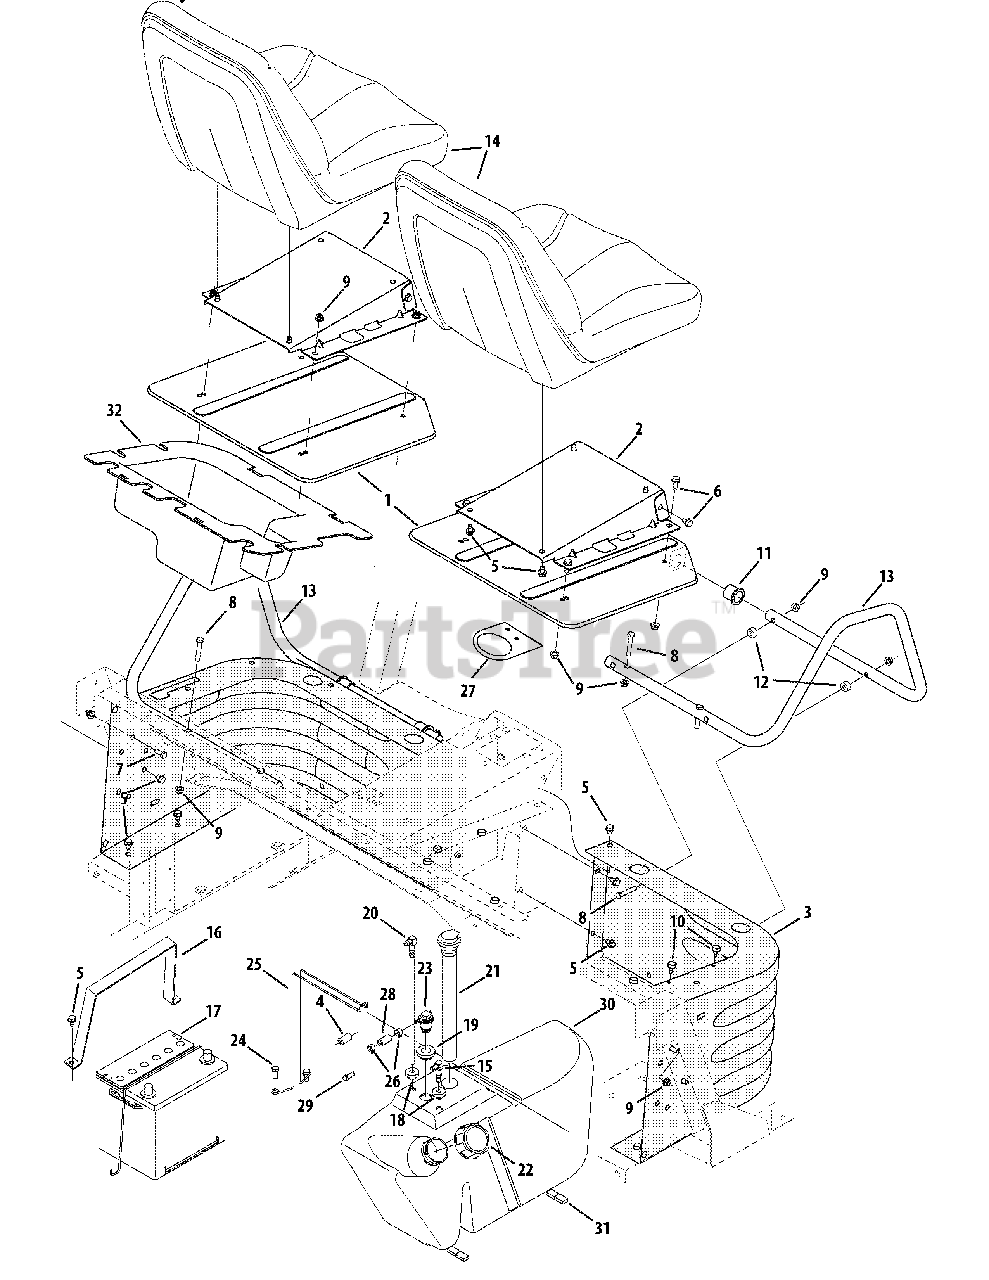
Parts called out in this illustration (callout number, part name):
1	Plt, Seat, Assm.
4	Line, Fuel, HP
5	Scr., TT, 5/16-18 x .500
6	Screw, LD, 5/16-18 x .750
7	Screw, 5/16-18 x .75
8	Screw, 5/16-18 x 1.75
9	Nut, Flglk, 5/16-18
10	Bmpr, .62 Dia. x .3
11	Brg, Flg, .894 ID x 1.1315 OD
12	Spcr, .315 x .750 x .375 Lg.
14	Seat, High Back
14	Seat, Sport
15	Ftg., Fuel, Pickup
16	Brkt., Mt., Battery
17	Battery, 450 CCA Dry
18	Bush, Tank, Gas
19	Bush, Tank, Vent
20	Ftg, Fuel, Pickup
21	Sensor, Fuel, Low
22	Cap, Fuel
23	Ftg, Fuel, Vent
24	Screw, 5/16-18 x .500
24	Screw, 5/16-18 x .75
25	Wire, tank, fuel
26	Clamp, Hose, .490 Dia.
27	Brkt., Tube, CVT
28	Fuel Line, 5/16 Id
28	Hose, Fuel Line, Low Permeation
29	Vent, 3/8 Dia.
30	Tank assembly, Fuel
31	Tape, .625 Wide X.25 Thk Foam
32	Tray, Seat box
